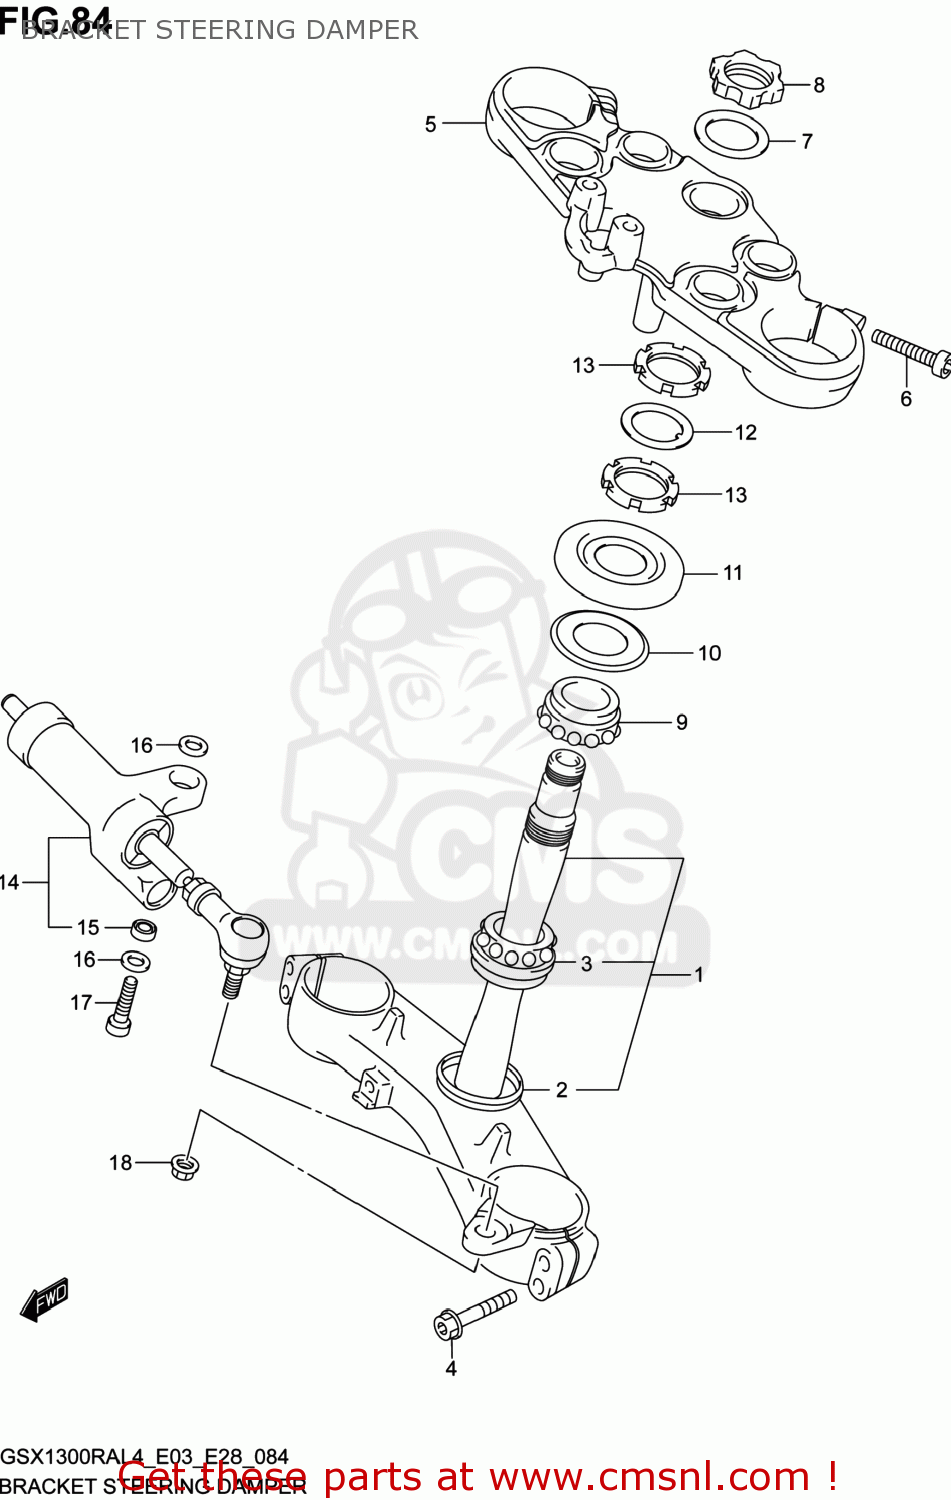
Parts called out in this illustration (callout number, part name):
1	BRACKET,FR FORK UNDER
2	SEAL,STEERING LWR
3	BEARING(30X55X17)
4	BOLT,AXLE STOPPER
5	BRACKET,FR FORK UPR
6	BOLT
7	WASHER
8	NUT
9	BEARING(30X55X17)
10	SEAL,STEERING LWR
11	COVER,STEERING UPR
12	WASHER,STEERING STEM
13	NUT,STEERING STEM
14	DAMPER ASSY,STEERING
15	BEARING(8X17.5X11)
16	SEAL,PILLOW BALL,DUST
17	BOLT
18	NUT
